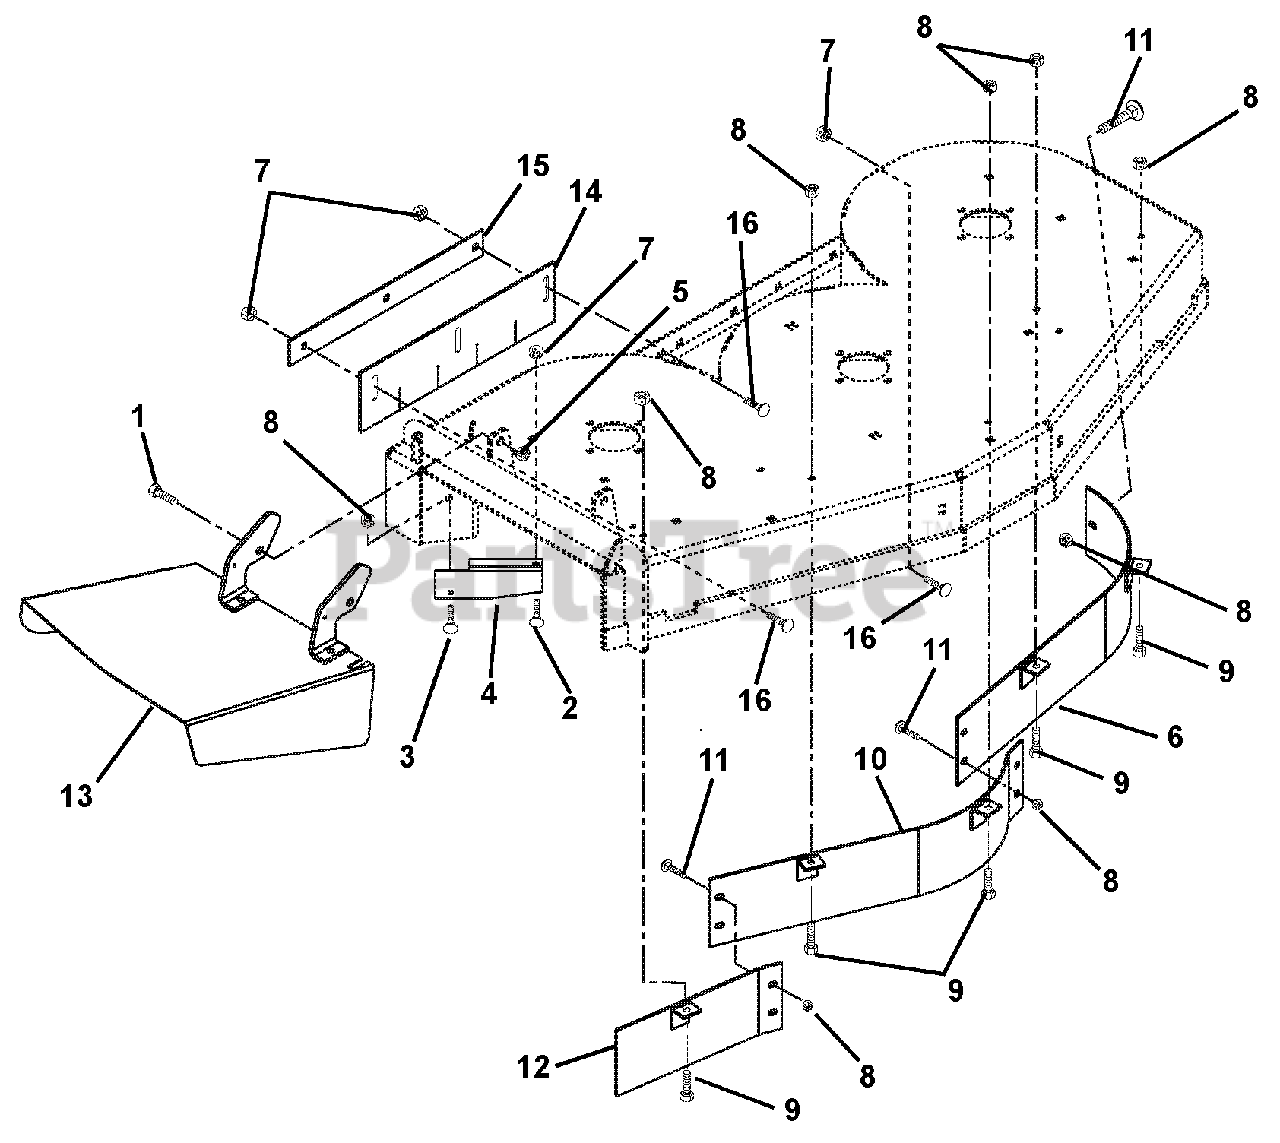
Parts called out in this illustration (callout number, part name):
1	Bolt-Hex .50-13 x 1.25 Grade 5
2	Bolt-Round Head Square Neck .38-16 x .75 Grade 5
3	Bolt-Round Head Square Neck .31-18 x 1.00 Grade 5
4	Deflector 44"/48" (108)
5	Nut-Locking-Nylon .50-13
6	Weldment- Upper Baffle Left (108)
7	Nut-Locking-Top-Flange .38-16
8	Nut-Locking-Top-Flange .31-18
9	Bolt-Hex .31-18 x .75 Grade 5
10	Weldment- Upper Baffle Center (108)
11	Bolt-Round Head Square Neck .31-18 x .75 Grade 5
12	Weldment, Right Hand Baffle-Upper (108)
13	Chute-Discharge
14	Skirt- Rubber
15	Strip- Striper Mount
16	Bolt-Round Head Square Neck .38-16 x 1.00 Grade 5
